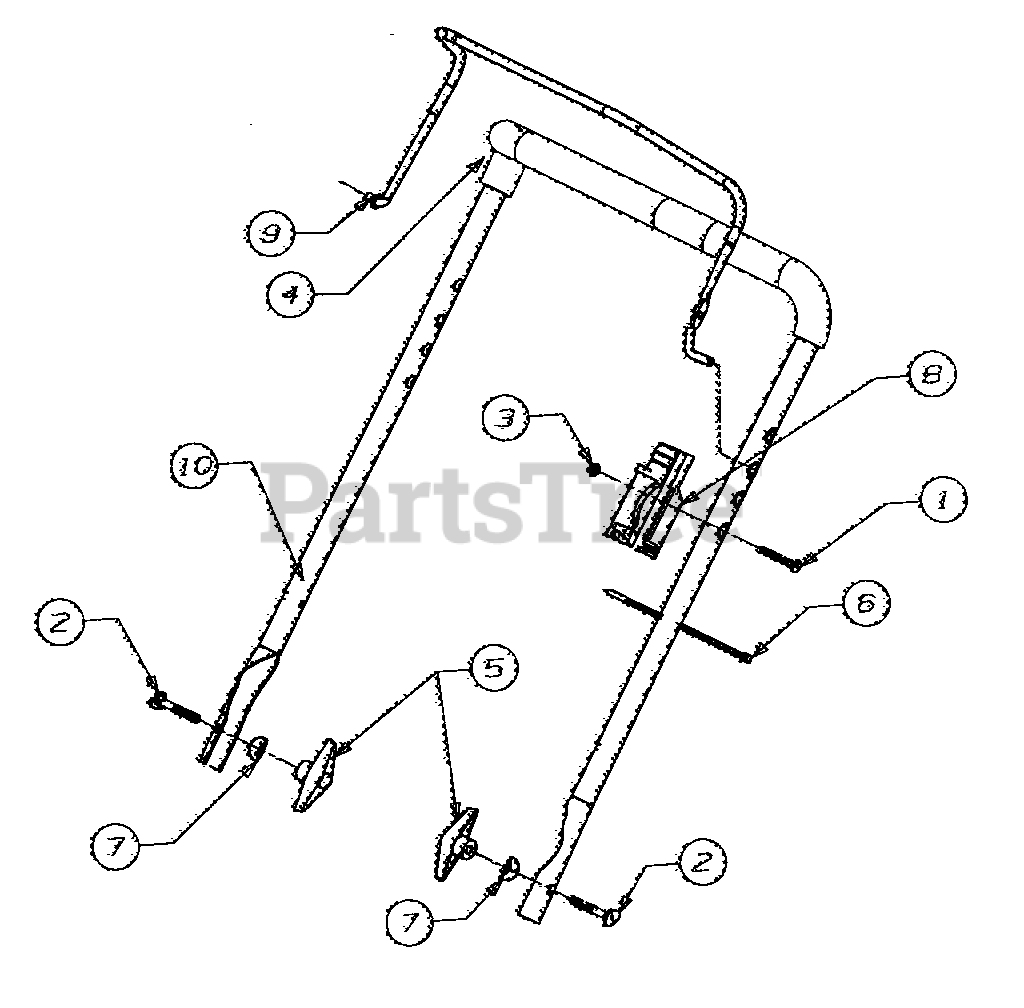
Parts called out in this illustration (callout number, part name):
1	Screw-Oval C-Sink L
2	Bolt-Carriage
3	Nut Insul. Lock
4	Grip Foam
5	Knob Handle
6	Tie Cable
7	Washer Saddle
8	Body-Lever Control
